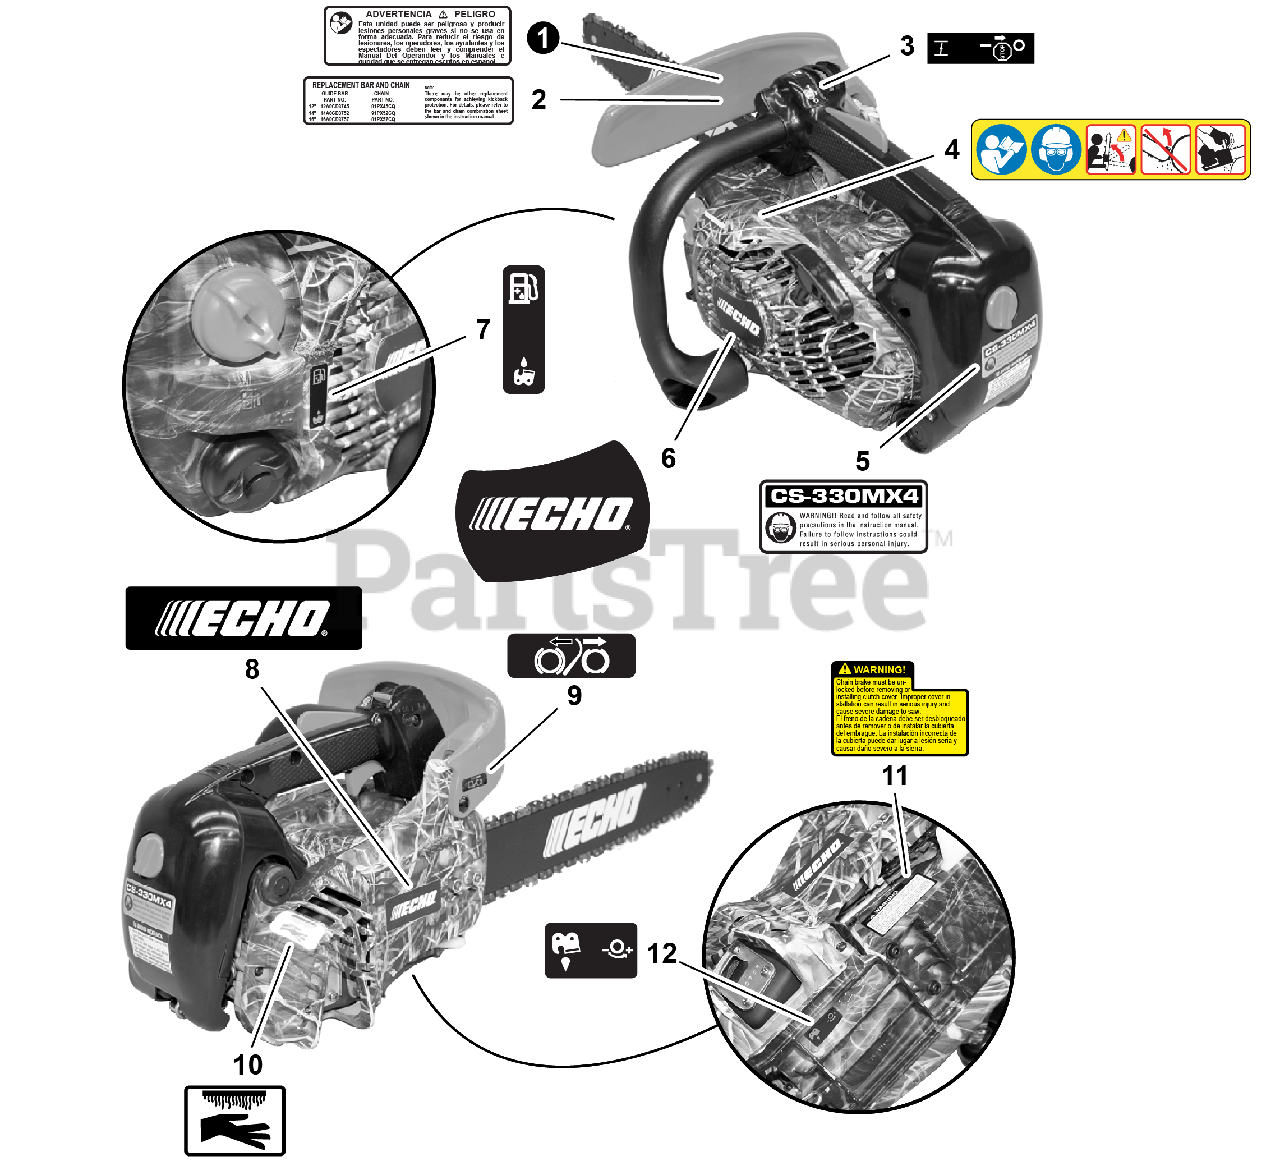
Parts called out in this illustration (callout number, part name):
1	LABEL, CAUTION
2	LABEL, BAR & CHAIN
4	LABEL, CAUTION
5	LABEL, MODEL
6	LABEL, ECHO
7	LABEL, FUEL - OIL
8	LABEL, ECHO
9	LABEL, CHAIN BRAKE
10	LABEL, CAUTION - HOT
11	LABEL, WARNING
12	LABEL, CHAIN OIL ADJUST
